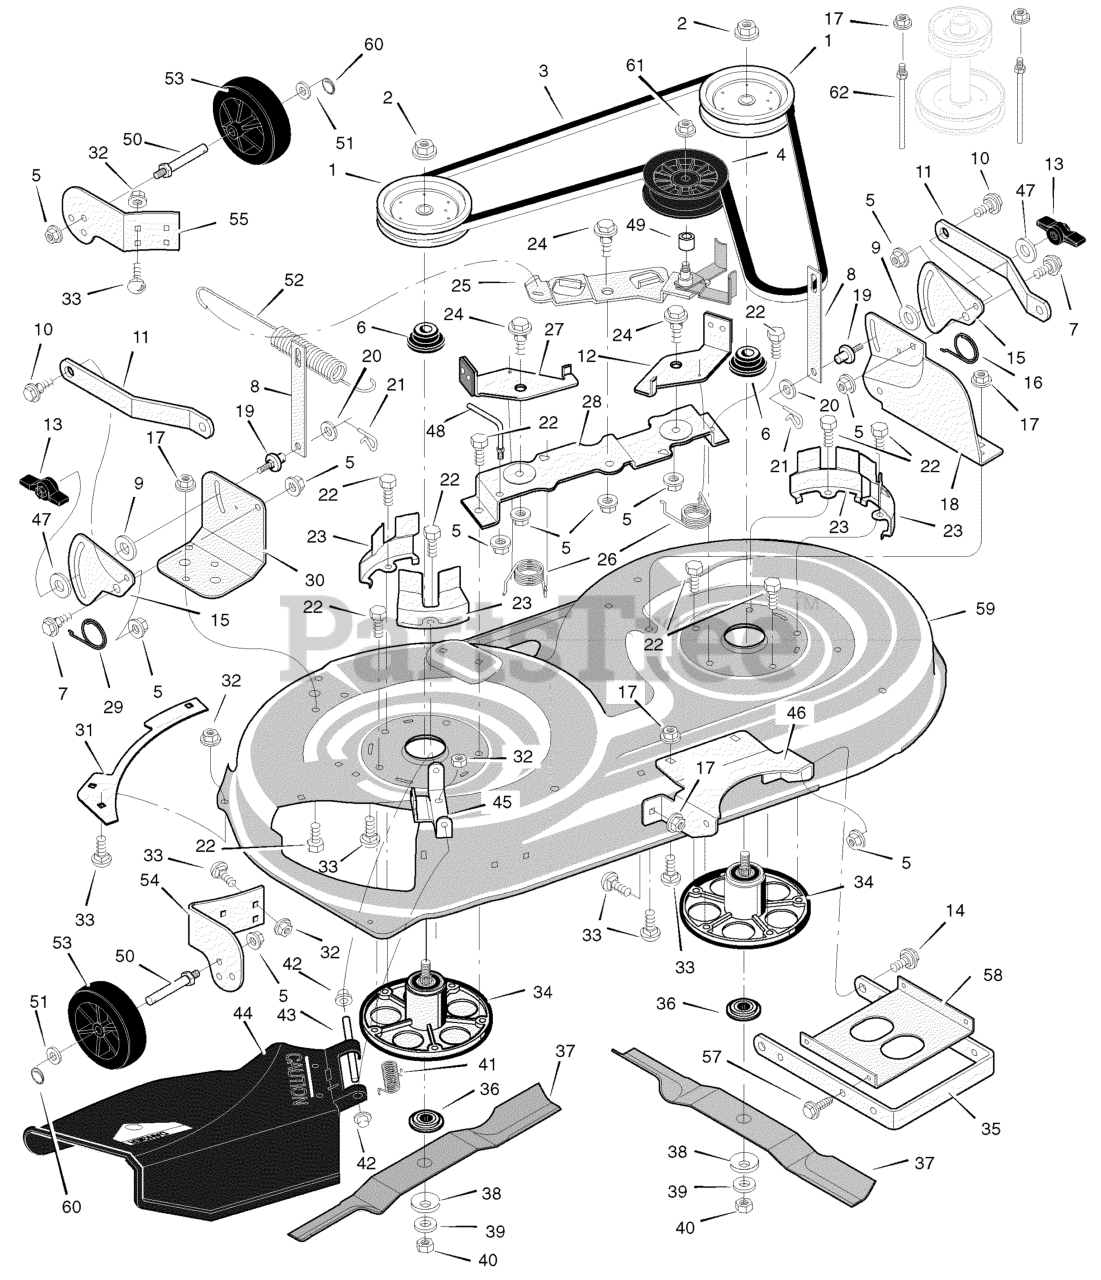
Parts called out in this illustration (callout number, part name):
1	Pulley, Jackshaft
2	Nut, Hex
3	Belt, Mower Drive
4	Pulley, Idler
5	Nut, Flange
6	Spacer, Pulley
7	Bolt, Shoulder
8	Link, Lift
9	Pad, Friction
10	Bolt, Shoulder
11	Bracket, Suspension
12	Pad Assembly, Left Brake
14	Bolt, Shoulder
15	Plate, Suspension
16	Spring
17	Nut, Flange
18	Bracket, Suspension
19	Pin, Hanger
20	Washer
21	Pin, Hair
22	Bolt
23	Cover, Pulley
24	Bolt, Shoulder
25	Arm, Idler
26	Spring
27	Pad Assembly, Right Brake
28	Bracket, Brake
29	Spring
30	Bracket, Suspension
31	Plate
32	Nut, Flange
33	Bolt, Carriage
34	Mandrell Housing
35	Bracket, Suspension
36	Adapter, Blade
38	Washer
39	Washer
40	Nut
41	Spring
42	Cap, Push On
43	ROD, Deflector
44	Deflector Assembly
45	Bracket, Deflector Hinge
46	Bracket, Front Hanger
47	Washer
48	Guide, Belt
49	Spacer
50	Bolt, Axle
51	Washer
52	Spring, Extension
53	Wheel, Gage
54	Bracket, Right Wheel
55	Bracket, Left Wheel
56	Bolt, Shoulder
57	Screw
58	Stiffener
59	Housing, Blade *
60	Ring, Locking
61	Nut, Flange
62	Guide, Belt
